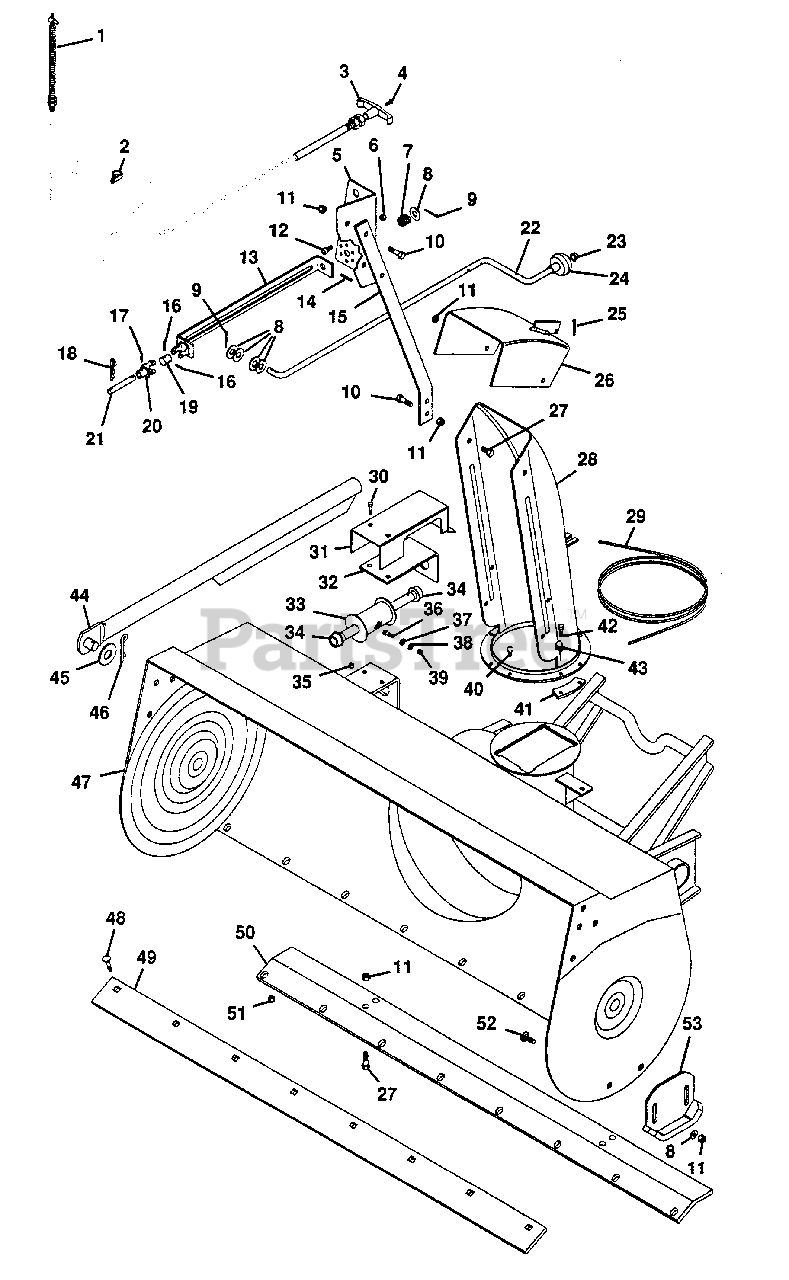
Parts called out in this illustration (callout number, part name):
1	Cable, Control
2	Clamp, Nylon
3	Knob, Black
4	Screw, Machine 8-32x.75 PHD
5	Bracket, Control
6	Nut, #10-24 Hex
7	Spring, Compression
8	Washer, Flat .406x.812x.065
9	Pin, Cotter .06x1.00
10	Bolt, Hex 3/8-16x1.00
11	Nut, Lock 3/8-16
12	Screw, SH #10-24x.375 Cap
13	Bracket, Slotted
14	Pin, Spring .187x1.500
15	Bracket, Bar Crank
16	Pin, Spring 1.87x1.000
17	Pin, Spring .125x.750
18	Hair Pin, Internal
19	Block, Universal
20	Half, Universal
21	Rod, Connector
22	Rod, Control
23	Cap
24	Knob
25	Pin, Cotter .09x.75
26	Deflector, Chute
27	Bolt, Hex 3/8-16x.75
28	Chute, Discharge
29	Cable
30	Bolt, Hex 1/4-20x1.00
32	Bracket, Spool
33	Spool
34	Bushing, Nylon .76x1x.6 Flg.
35	Nut, Lock 1/4-20
36	Bolt, 1/4-20x.625 Rd Hd Sq Nk
37	Washer, Lock Special 5/16 I.D.
38	Washer, Flat .281x.625x.065
39	Nut, Hex 1/4-20
40	Screw, Tapping 10-24x.50 HHD
41	Clamp, Chute
42	Screw, Taptite 10-24x.75
43	Clamp, Cable
44	Weldment, Push Rod
45	Washer, Flat .812x1.469x.134
46	Pin, Hair
47	Housing, 40" Snowblower
47	Housing, 48" Snowblower
48	Bolt, Carriage 5/16-18x.875
49	Blade, Scraper 48"
49	Blade, Scraper 40"
50	Brace, Scraper Blade 48"
50	Brace, Scraper Blade 40"
51	Nut, Lock 5/16-18
52	Bolt, 3/8-16x1.00 Rd Hd Sq Nk
53	Runner, Skid Shoe
